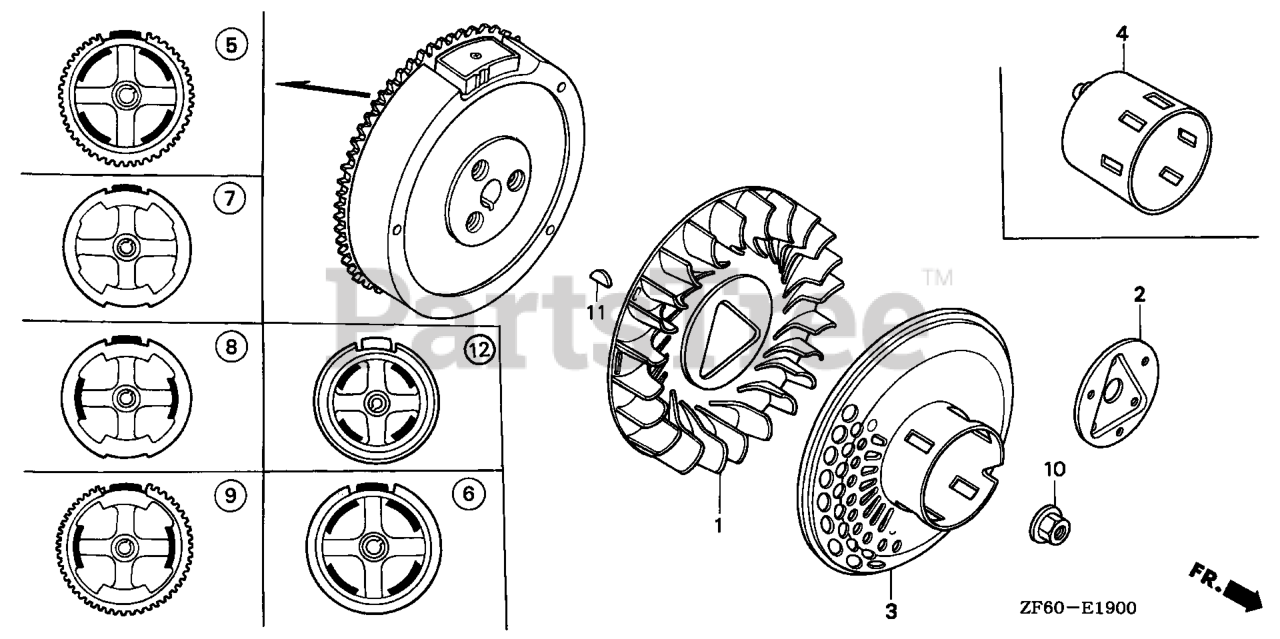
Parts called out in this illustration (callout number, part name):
1	FAN, COOLING
3	PULLEY, STARTER (SCREEN GRID)
7	FLYWHEEL
10	NUT, SPECIAL (16MM) (1)
10	NUT, SPECIAL (16MM)
11	KEY, SPECIAL WOODRUFF (25X18)
